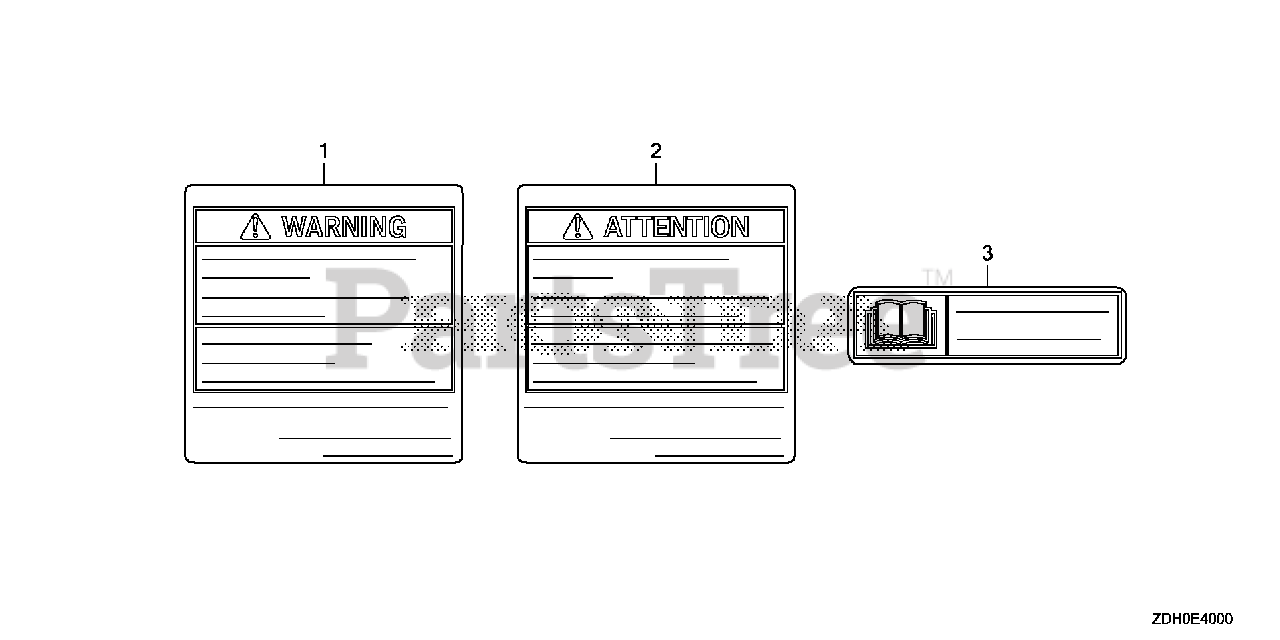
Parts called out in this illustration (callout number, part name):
1	MARK, OPERATOR CAUTION (ENGLISH)
2	MARK, OPERATOR CAUTION (FRENCH)
3	LABEL, CAUTION (CHINA)
